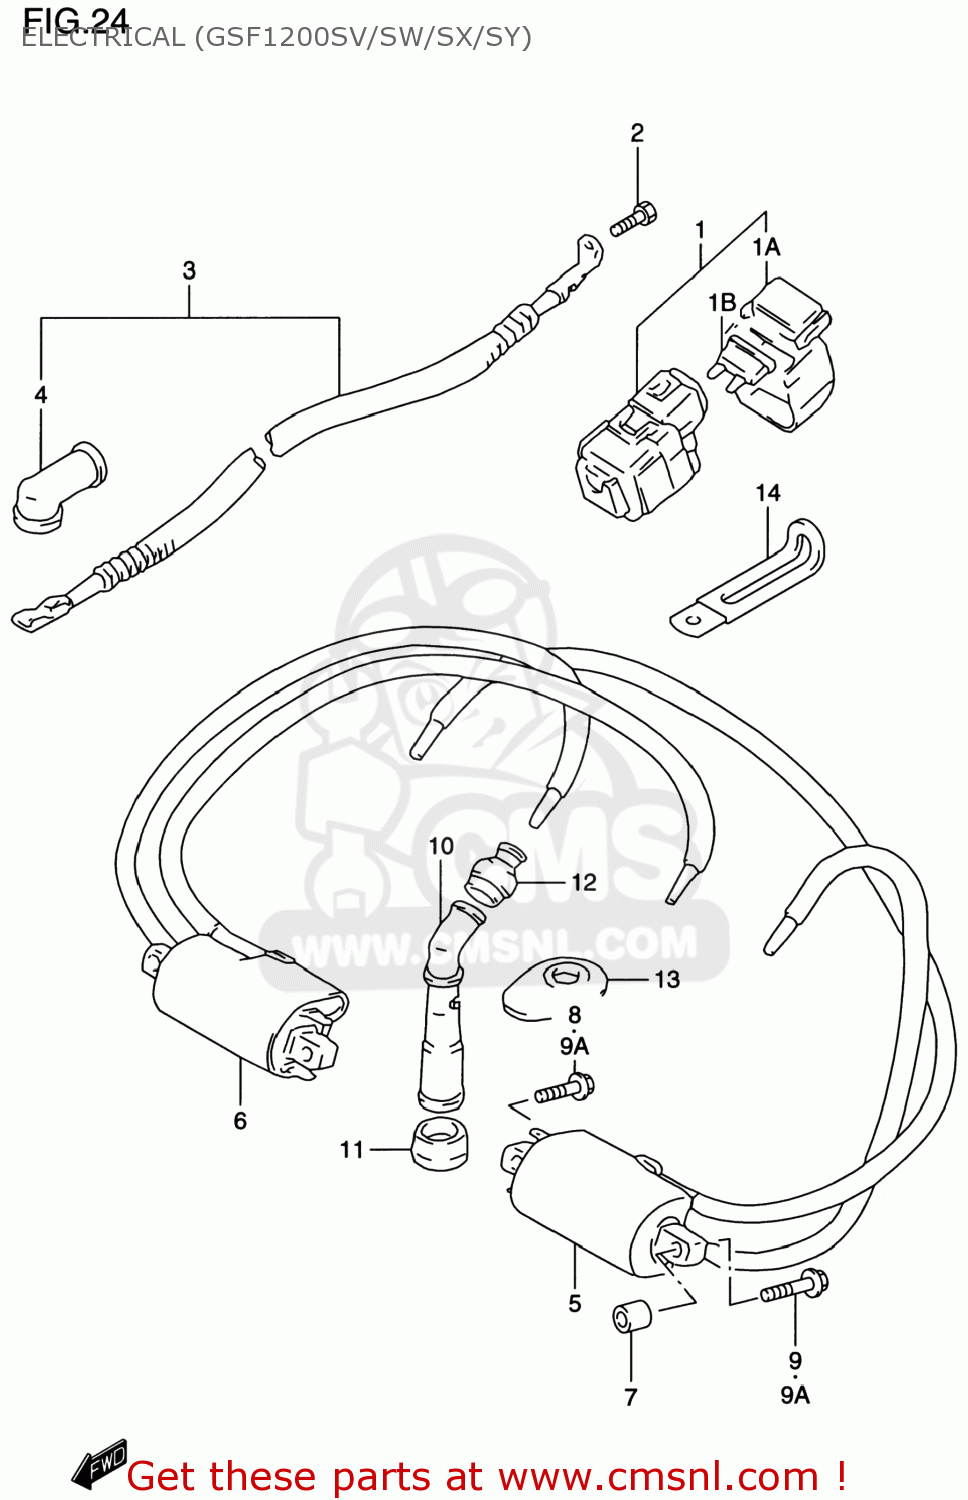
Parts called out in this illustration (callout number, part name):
1	RELAY ASSY,STARTING MOTOR
1A	COVER,STARTER RELAY
1B	FUSE(30A)
2	SCREW(6X8)
3	WIRE,STARTER MOTOR LEAD
4	CAP,STARTER MOTOR LEAD
5	COIL ASSY,IGNITION
6	COIL ASSY,IGNITION
7	SPACER(6X12X10)
8	BOLT
9	BOLT
9A	BOLT
10	CAP,SPARK PLUG
11	SEAL,SPARK PLUG CAP
12	SEAL,HIGH TENSION CORD
13	COVER,SPARK PLUG CAP
14	CLAMP(L:65)
